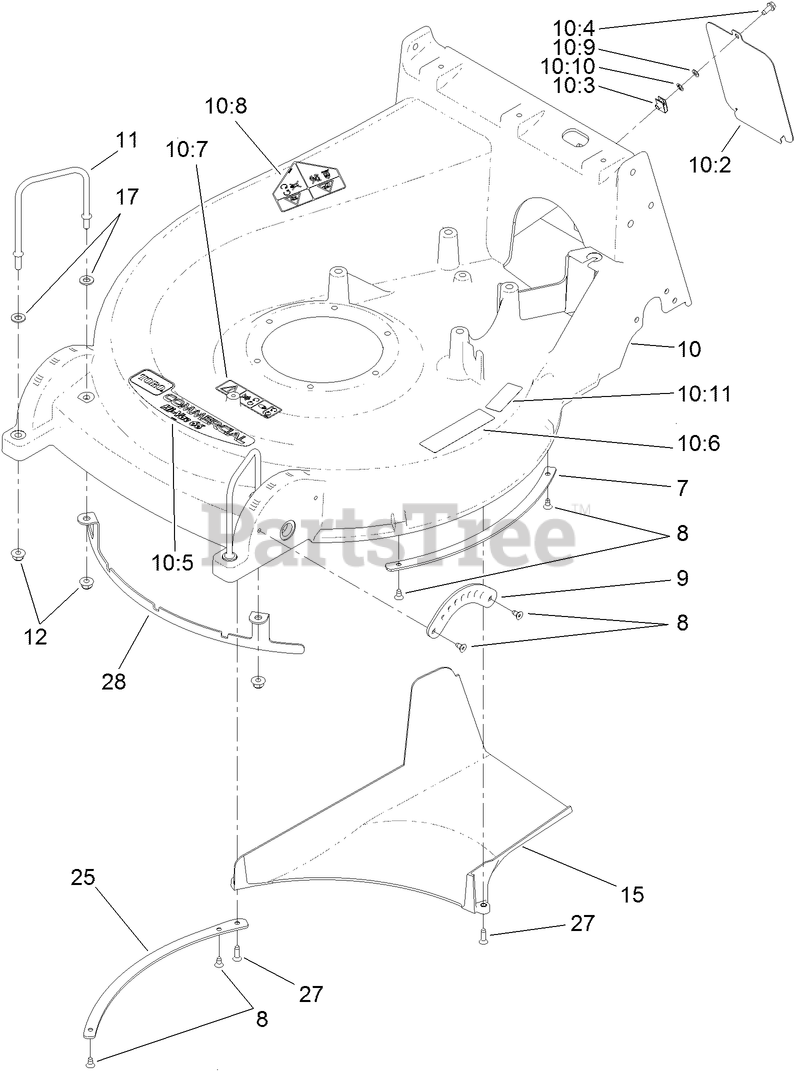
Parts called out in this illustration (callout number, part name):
7	PLATE-SKID, 10 GAGE
9	QUADRANT-FRONT
10	DECK ASM
10:2	COVER-ACCESS, AXLE
10:4	SCREW-HWH
10:6	DECAL-DANGER
10:7	DECAL-MISSING, COVER
10:8	DECAL-DANGER
10:9	WASHER-FLAT
10:10	NUT-RETAINER
10:11	DECAL-WARNING, BLOCK
11	HANDLE-DECK
12	NUT-HF, NI
15	PLASTIC CHUTE KIT (W/SCREWS)
17	WASHER-FLAT
25	PLATE-SKID
27	SCREW-TORX
28	GUARD-FRONT BLADE
